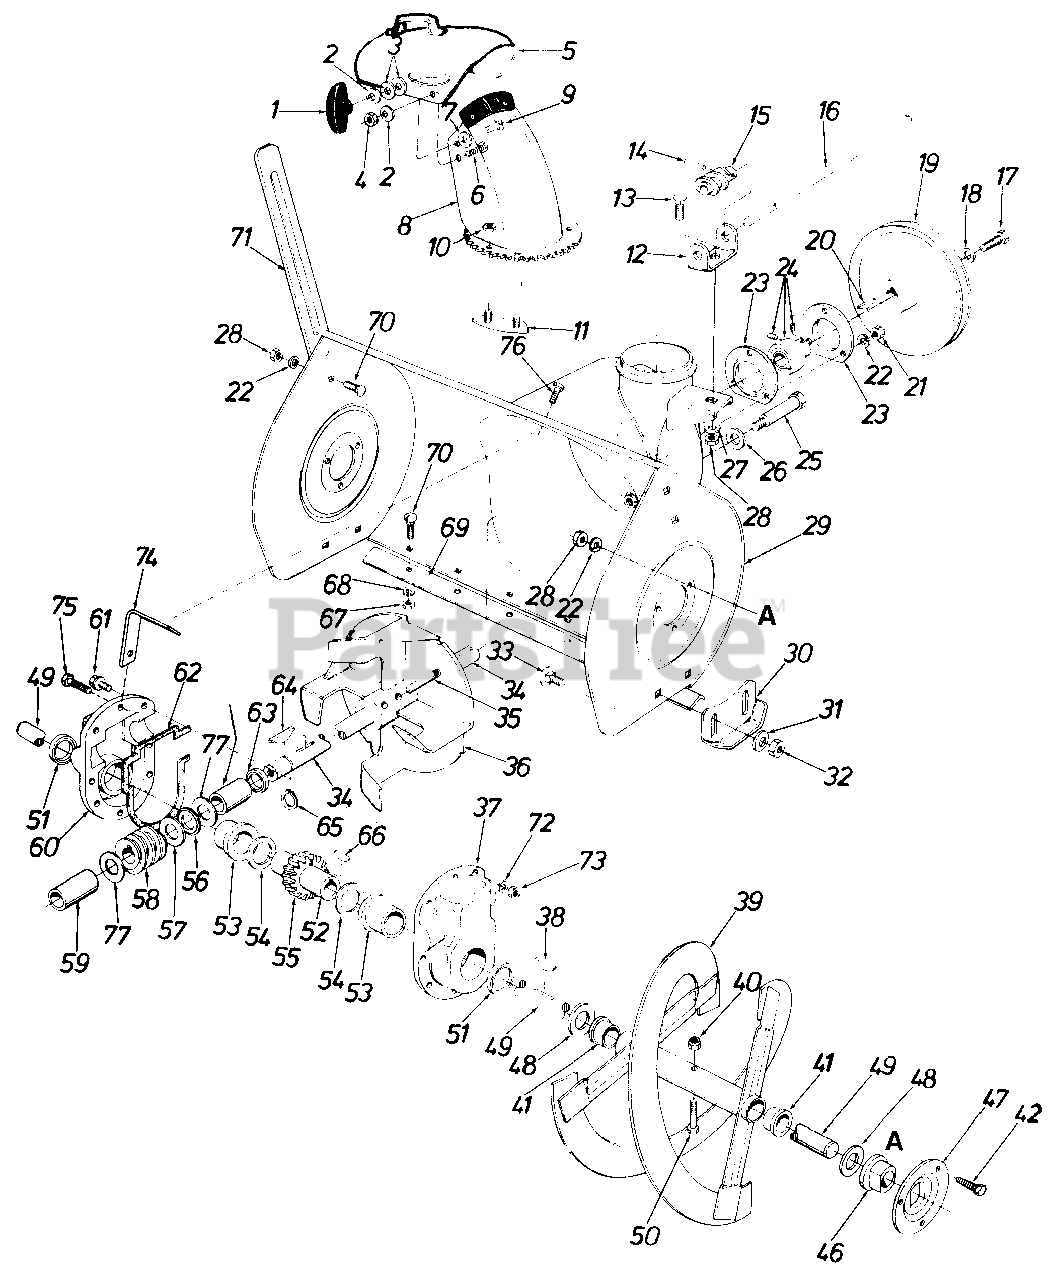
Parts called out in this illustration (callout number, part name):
1	Hand Knob Ass'y.
2	Bell-Wash. .345 I.D. x .88 O.D. x .060
3	Fl-Wash. .312 I.D. x 1.125 O.D. x .125
4	Hex Cent. L-Nut 5/16-18 Thd.
5	Top Chute Ass'y.
6	Carr. Bolt 5/16-18 x .62" Lg.
7	Fl-Wash. .53 I.D. x 1.25 O.D. x .100
8	Chute Ass'y.
9	Carr. Bolt 5/16-18 x 1.00" Lg.
10	Hex Cent. L-Nut 1/2-20 Thd.
11	Chute Flange Keeper Ass'y.
12	Chute Brkt.
13	Carr. Bolt 5/16-18 x .62" Lg.
14	Spring Pin Roll 1/8" Dia. x .75" Lg.
15	Worm - R.H. w/Three Threads
16	Chute Crank .38" Dia. x 41.0" Lg.
17	Hex L-Scr. 5/16-18 x .88" Lg.
18	Bell-Wash. .345 I.D. x .88 O.D. x .060
19	V-Pulley .875 I.D. x 10.12 O.D.
20	#9 Hi-Pro Key 3/16 x 3/4" Dia.
21	Hex Nut 5/16-18 Thd.
22	L-Wash. 5/16" Scr.
23	Bearing Hsg. - Self Aligning Brg.
24	Self Aligning Brg. .875 I.D.
25	Stud 3/8-16 x 2.75" Lg.
26	Bell-Wash. .400 I.D. x .88 O.D. x .060
27	Bell-Wash. .345 I.D. x .88 O.D. x .060
28	Hex Nut 5/16-18 Thd.
29	Blower Hsg. Ass'y.
30	Slide Shoe
31	Bell-Wash. .400 I.D. x .88 OD x.060
32	Hex Nut 3/8-16 Thd.
33	Carr. Bolt 3/8-16 x .75" Lg.
34	Blower Axle
35	Spring Pin Spiral 5/16" Dia. x 1.75" Lg.
38	#91 Woodruff Key 1/4" x 3/4" Dia.
41	Plastic Bushing
42	Hex Sems Scr. 5/16-18 x .75" Lg.
46	Flange Brg. w/Flats 1.00" I.D.
47	Bearing Hsg.- Spiral Hsg.
48	Fl-Wash. 1.06 I.D. x 1.75" O.D.x .100
49	Spiral Axle - 26"
50	Hex Scr. 5/16-18 x 1.75" Lg.
51	Oil Seal 1.50" I.D.
52	Worm Gear Shaft
53	Flange Brg. 1.503 I.D.
54	Fl-Wash. 1.50 I.D. x 2.00 O.D. x .030
55	Double Threaded Worm Gear
56	Thrust Brg. .88 I.D. x 1.44 O.D x .078
57	Fl-Wash. .88 I.D. x 1.40 O.D. x .150
58	Double Threaded Worm - L.H.
59	Sleeve Brg .875 I.D.
60	Complete Gear Hsg. Half - R.H.
61	Hex Scr. 5/16-18 x 1.00" Lg.
62	Gasket
63	Oil Seal .875" I.D.
64	#9 Hi-Pro Key 3/16 x 3/4" Dia.
65	Snap Ring for .875" Dia. Shaft
66	#91 Woodruff Key 1/4 x 3/4" Dia.
67	Hex Nut 5/16-18 Thd.
68	L-Wash. 5/16" Scr.
70	Carr. Bolt 5/16-18 x .62" Lg.
71	Drift Cutter
72	Wave Wash. 5/16" Scr.
73	Hex Ins. L-Nut 5/16-18 Thd.
74	Gear Hsg. Support Brkt.
75	Hex Scr. 5/16-18 x 1.25" Lg.
76	Hex Wash. Hd. Self-Tap Scr. 5/16-24 x .50" Lg.
77	Fl-Wash. .88 I.D. x 1.40 O.D. x .150
